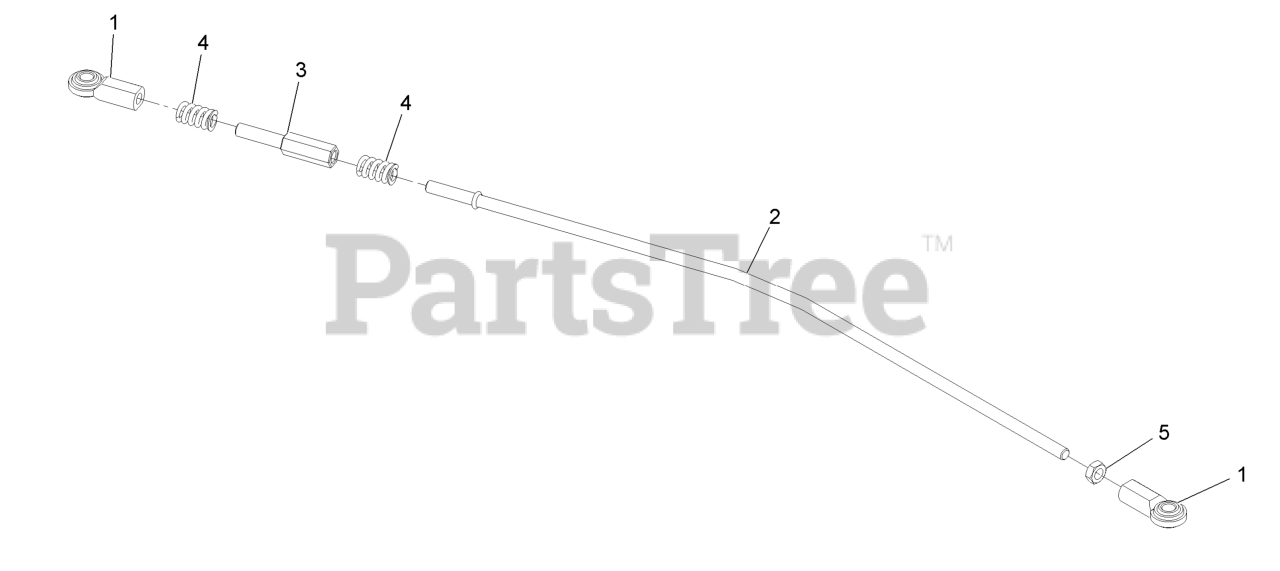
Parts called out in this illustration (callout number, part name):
1	JOINT-BALL, END
2	LINK-LOWER, MOTION CONTRO
3	ROD-ADJUSTMENT
4	SPRING-COMPRESSION
5	NUT-HJ
